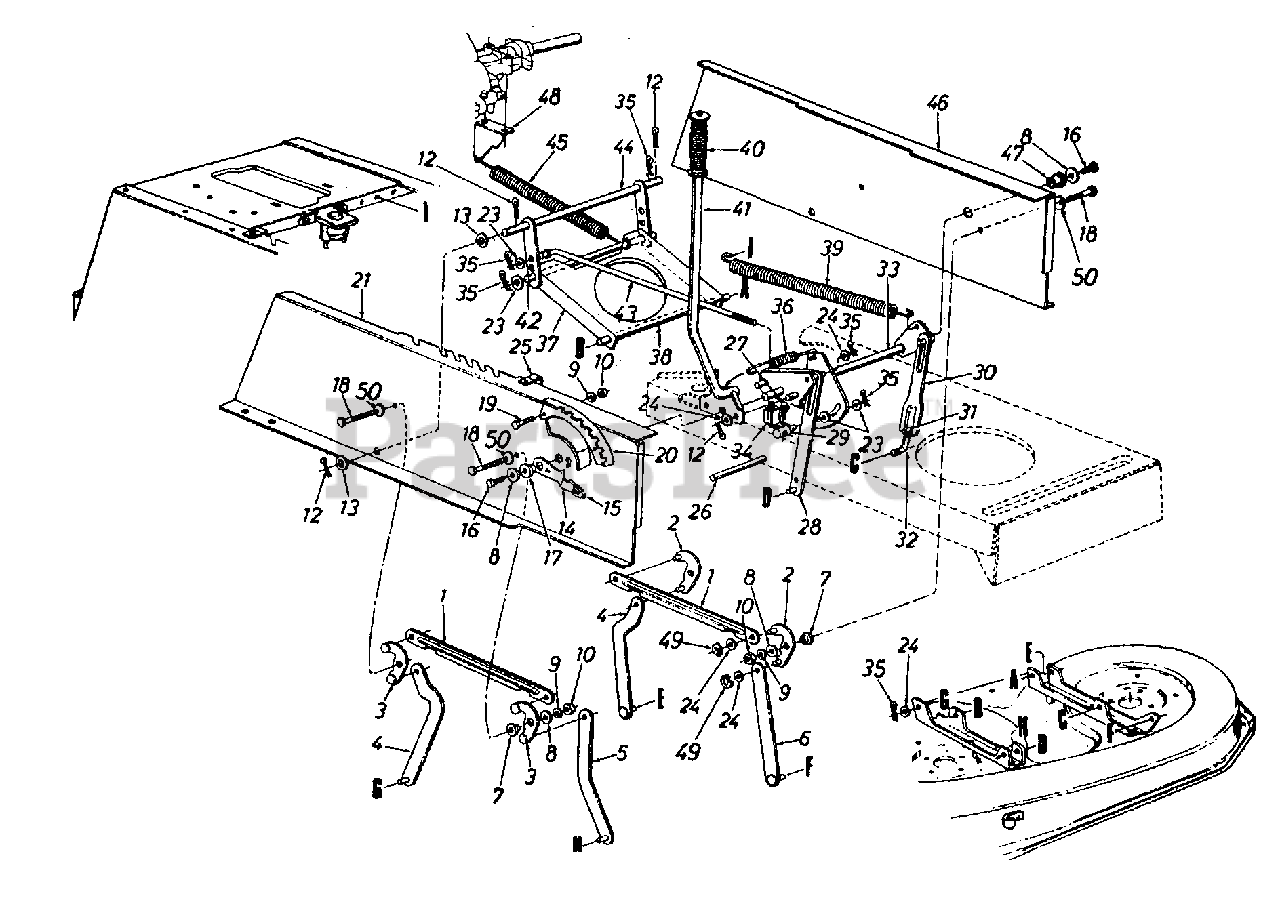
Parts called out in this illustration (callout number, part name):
1	Connecting Rod
2	Pivot Link Ass'y.-L.H.
3	Pivot Link Ass'y.-R.H.
4	Deck Hanger Link Ass'y.
5	Deck Hanger Link Ass'y.
6	Deck Hanger Link Ass'y.
7	Shld. Spacer.318" I.D.
8	Fl-Wash. .344" I.D. x 1.125" O.D.
9	L-Wash. 5/16" I.D.
10	Flange Lock Nut 5/16-18 Thd. (Gr. 5)
12	Cotter Pin 1/8" Dia.
13	Fl-Wash. .635" I.D. x 1.0" O.D.
14	Hgt Adj. Stop Lever Ass'y.
15	Knob
16	Hex Wash. TT Tap Scr.5/16-18 x .75"
17	Flange Brg. .63" I.D.
18	Hex Wash. Hd. Scr. 5/16-18x .875" Lg.
19	Hex Bolt 5/16-18 x .75" Lg.
20	Index Brkt.
24	Fl-Wash. .531" I.D. x .93" O.D.
25	Clamp
26	Running Board Rod
27	Hex Wash. Hd. Tap Scr.
28	Link Deck Lift Ass'y.
29	Adj. Ferrule 3/8-24 Thd.
30	Adj. Deck Lift Link
31	Hex Nut 1/2-20 Thd. (Gr. 5)
32	Lift Link Adjuster
35	Inter. Cotter Pin 3/8" Dia.
36	Extension Spring
37	Stabilizer Bracket
38	Shaft 1/2" Dia. x 10.28" Lg.
39	Extension Spring
40	Grip (Lift Handle)
43	Disengagement Rod
44	Stabilizer Shaft Ass'y.
45	Extension Spring 7.58" Lg.
48	Spring Retainer Brkt.
49	E-Ring
50	Bell-Wash. .325" I.D.
